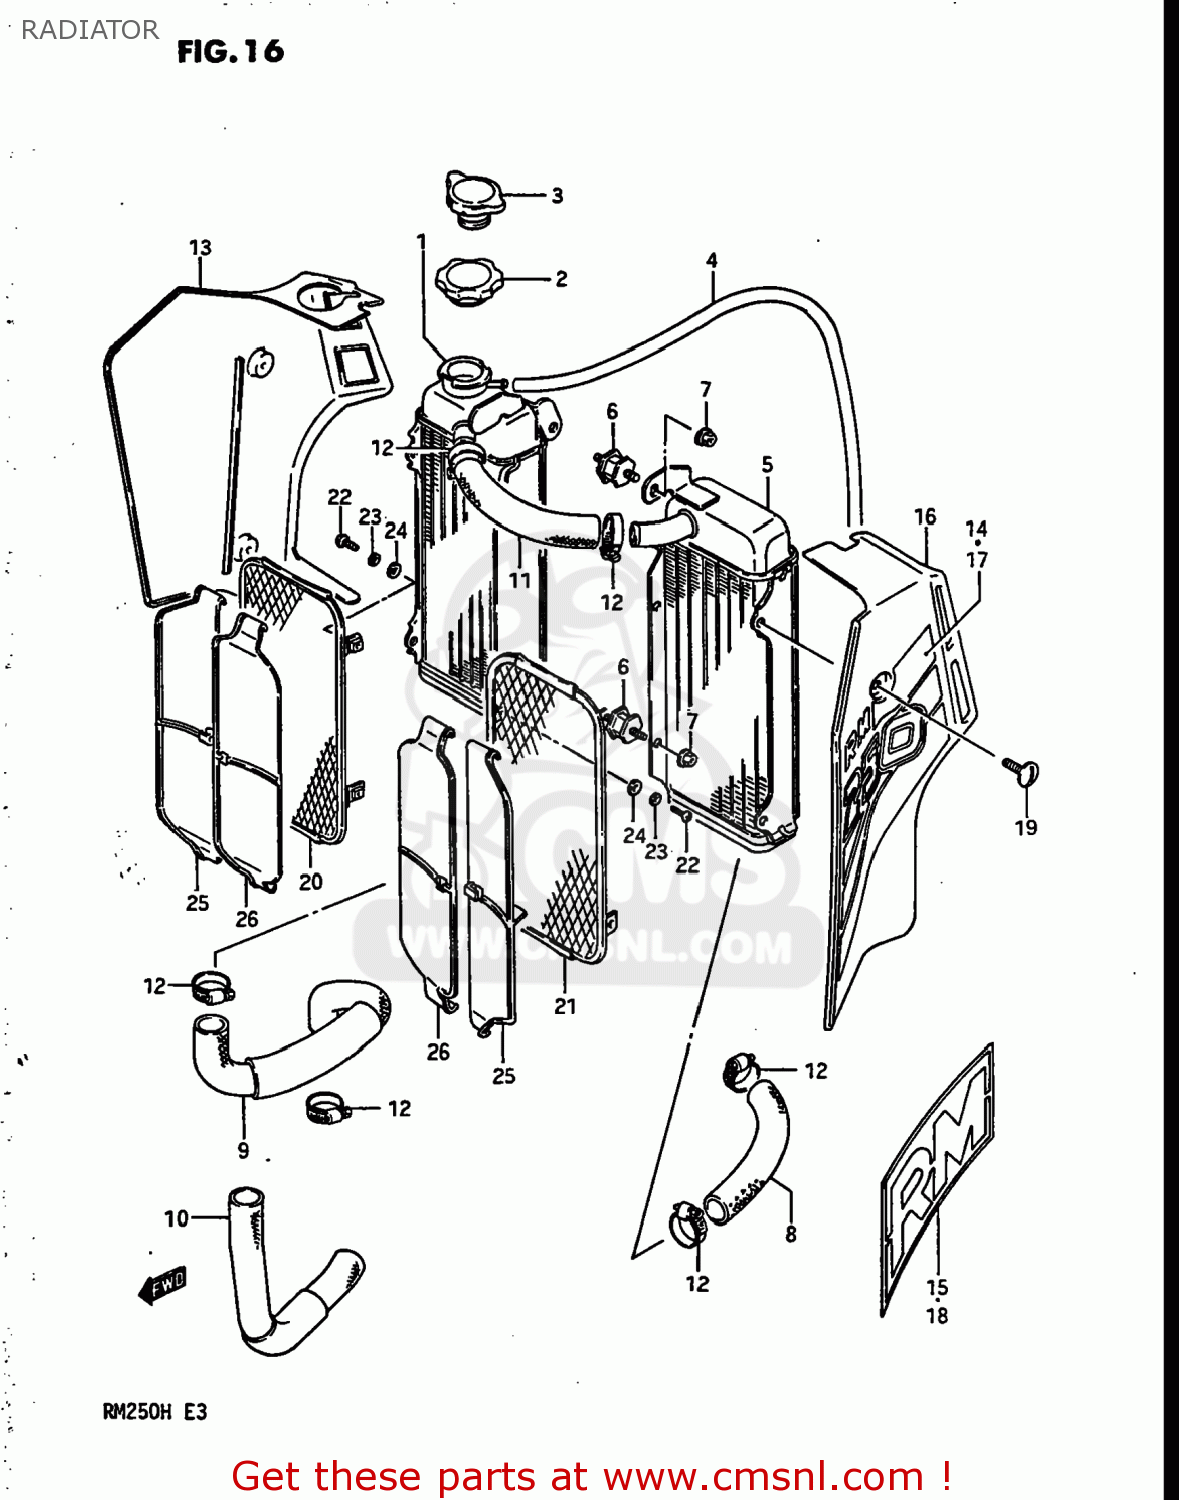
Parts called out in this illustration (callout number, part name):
1	RADIATOR COMP,WATER,RIGHT
2	CAP,RADIATOR 1.1
3	CAP,RADIATOR 1.1
4	HOSE
5	RADIATOR COMP,WATER,LEFT
6	BOLT,RADIATOR CUSHION
7	NUT 6MM
8	HOSE,RADIATOR INLET
9	HOSE,RADIATOR OUTLET
10	HOSE,RADIATOR OUTLET
11	HOSE,RADIATOR JOINT
12	CLAMP
13	COVER,RADIATOR
14	TAPE SET,RADIATOR COVER
15	TAPE SET,RADIATOR COVER STRIPE
16	COVER,RADIATOR
17	TAPE SET,RADIATOR COVER
18	TAPE SET,RADIATOR COVER STRIPE
19	SCREW(6X14)
20	BUMPER,RADIATOR,RIGHT
21	BUMPER,RADIATOR,LEFT
22	SCREW
23	WASHER,LOCK
24	WASHER
25	LOUVER,RADIATOR NO.1
26	LOUVER,RADIATOR NO.2
